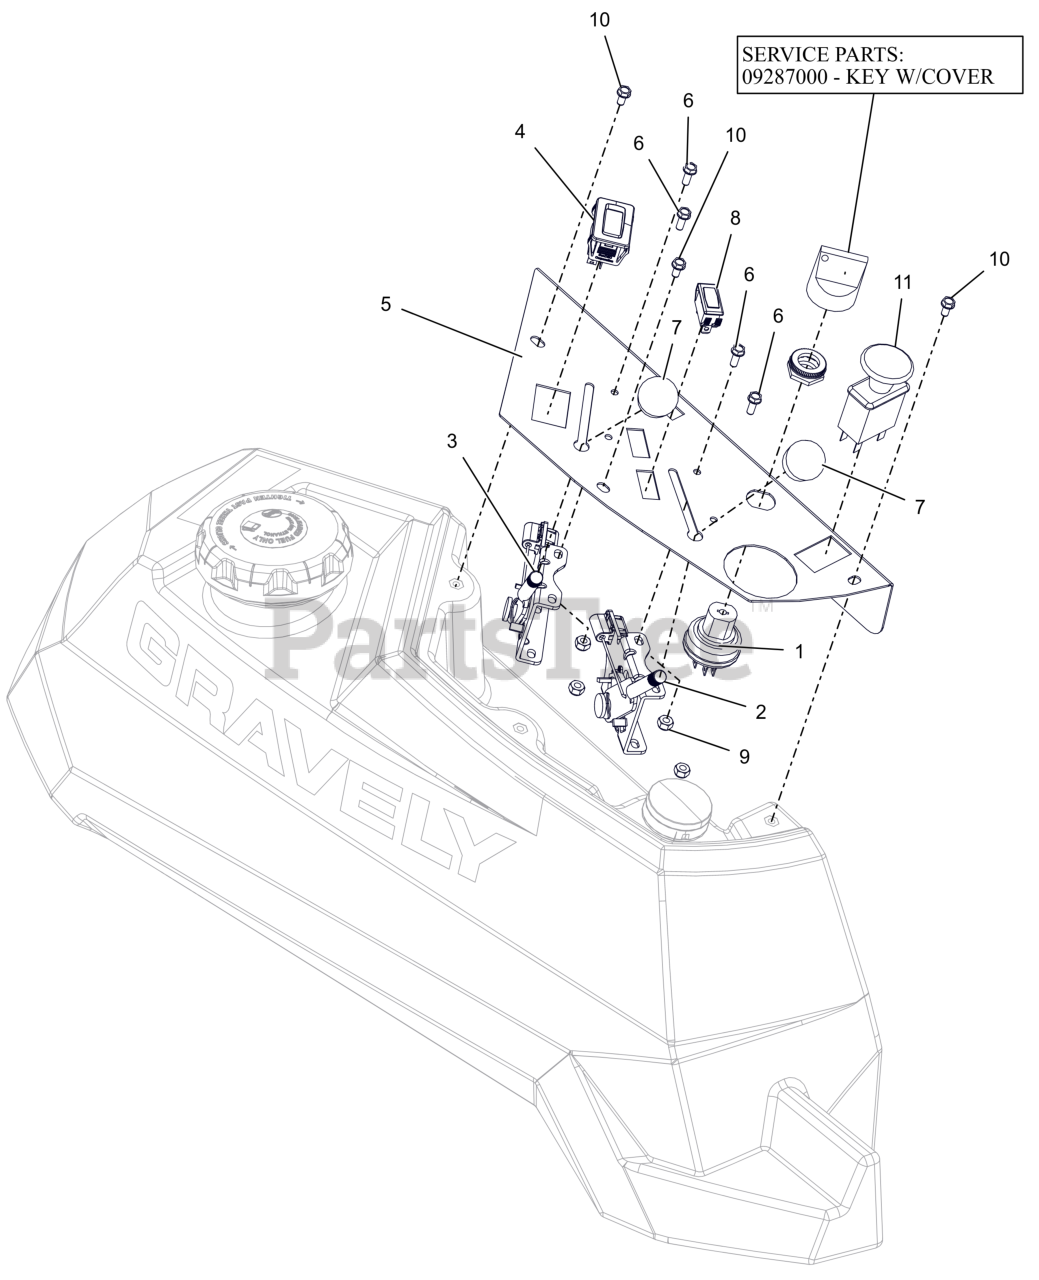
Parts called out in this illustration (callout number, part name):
1	SWITCH, IGNITION
1	KEY, W/ SHIELD
2	CABLE, PRO-CTRL 35.50"
3	CABLE, PRO-CONTROL 31.50"
4	HOUR METER
5	PT100 CONTROL PANEL - RED
6	BLT, HWH #10-24X.50 ZCC
7	KNOB-CONTROL-BLACK .38-16X.50
8	LIGHT, INDICATOR (RED)
9	NUT-LK-NYL #10-24 G2 ZCC
10	SCR-MCH 10-24X.38 HWHSTAINLESS
11	SWITCH, CLUTCH
